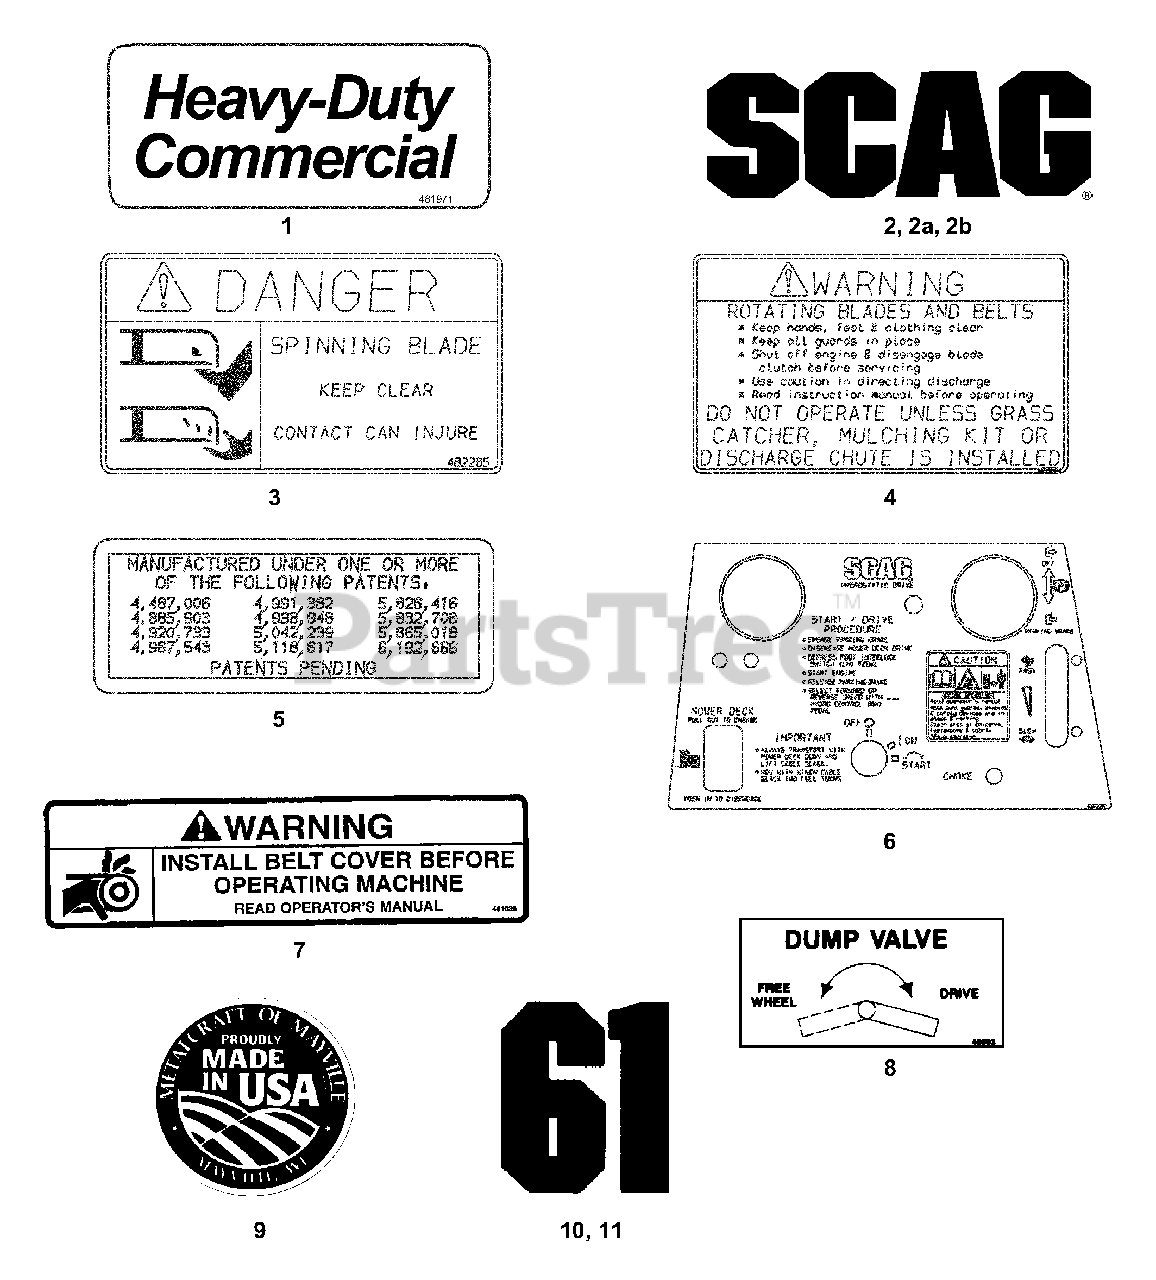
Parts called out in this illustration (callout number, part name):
1	Decal, Heavy Duty Commercial
2	Decal, Scag Logo ( Cutter Deck)
2A	Decal, Scag Logo (Battery Box Front)
2B	Decal, Scag Logo Seat Back
3	Decal, Danger-Spinning Blades
4	Decal, Warning-Rotating Blades
5	Decal, Patent
6	Decal, Instrument Panel
7	Decal, Warning-Belt Cover
8	Decal, Dump Valve
9	Decal, Metalcraft-Made In USA
10	Decal, 61 Advantage
11	Decal, 72 Advantage
